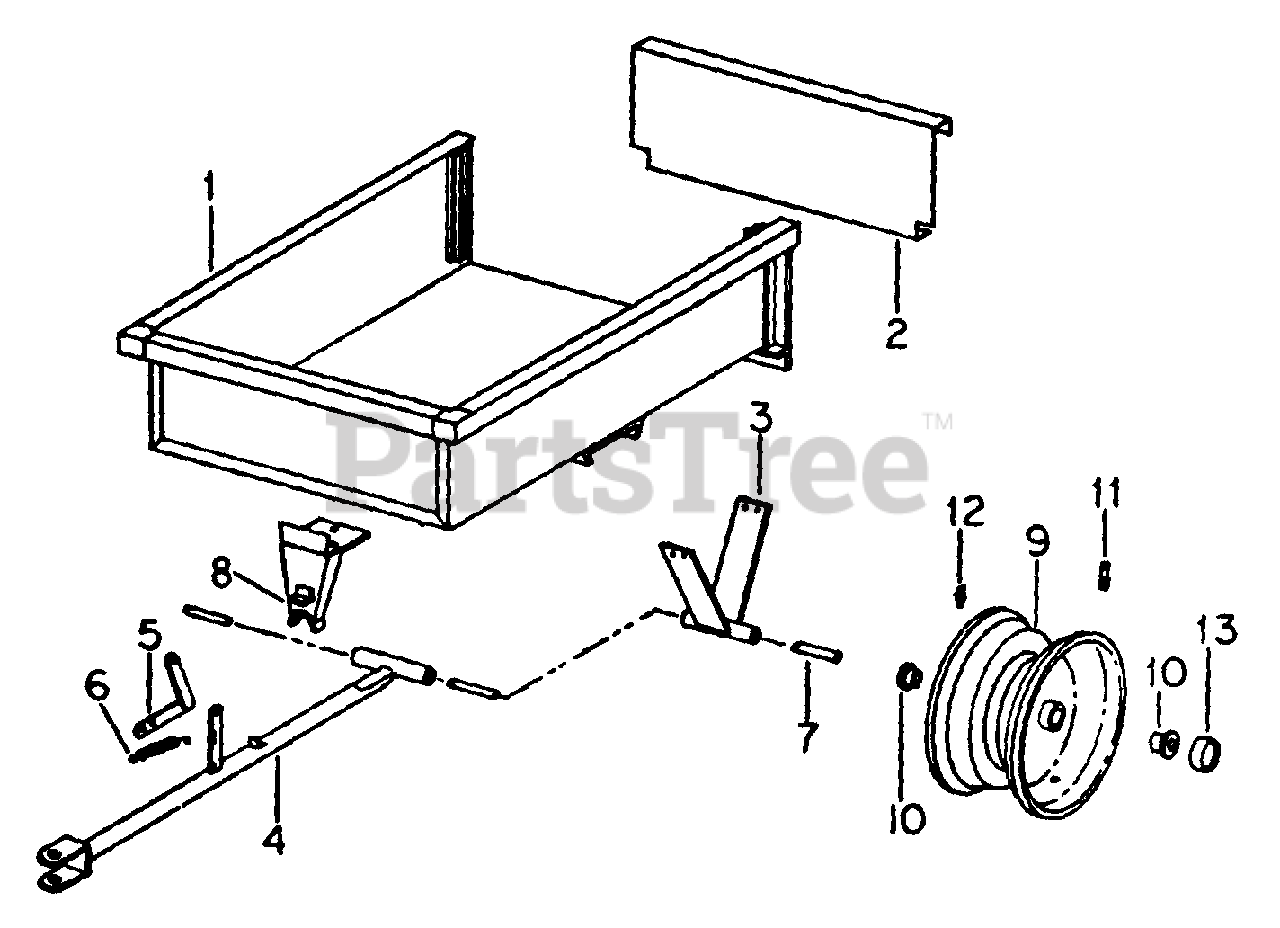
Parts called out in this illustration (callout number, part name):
3	SUPPORT, AXLE
6	SPRING, LATCH RETURN
8	SPACER LATCH
9	WHEEL W/OUT TIRE
11	VALVE, TR413 TUBELESS TIRE RIM
12	FITTING, 1/4-28 STR LUB
